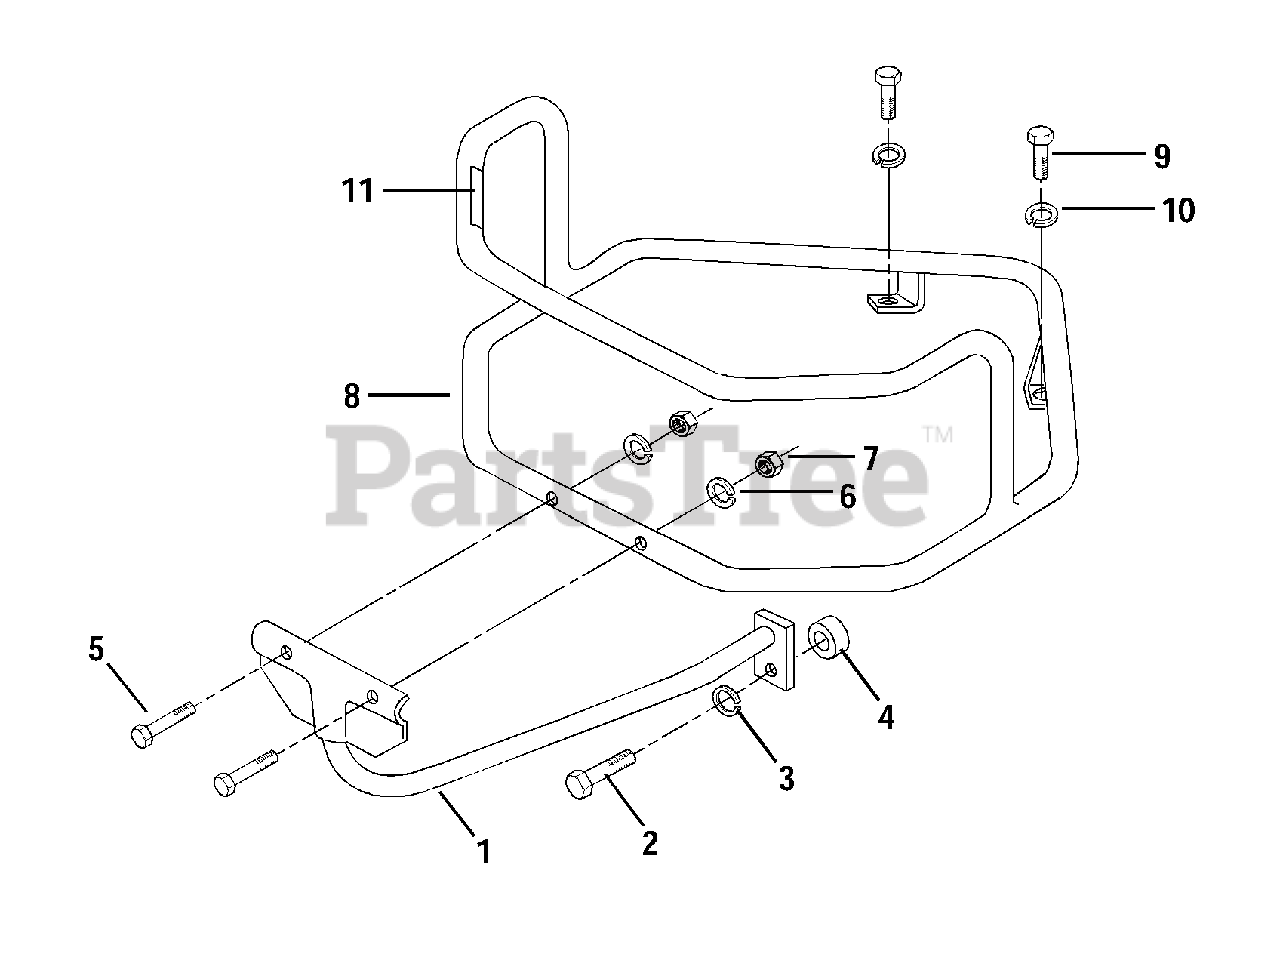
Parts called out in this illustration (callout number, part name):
1	Brace - bumper bottom
2	Bolt - hex hd., 1/2-13 x 1-1/2"
3	Lockwasher - spring lock, 1/2"
4	Spacer, 1/2"
5	Bolt - hex hd., 5/16-18 x 1-1/2"
6	Lockwasher - spring lock, 5/16"
7	Nut - hex, 5/16"-18
8	Bumper wraparound
9	Bolt - hex hd., 3/8-16 x 1"
10	Lockwasher - spring lock, 3/8"
11	Decal - for bumper
